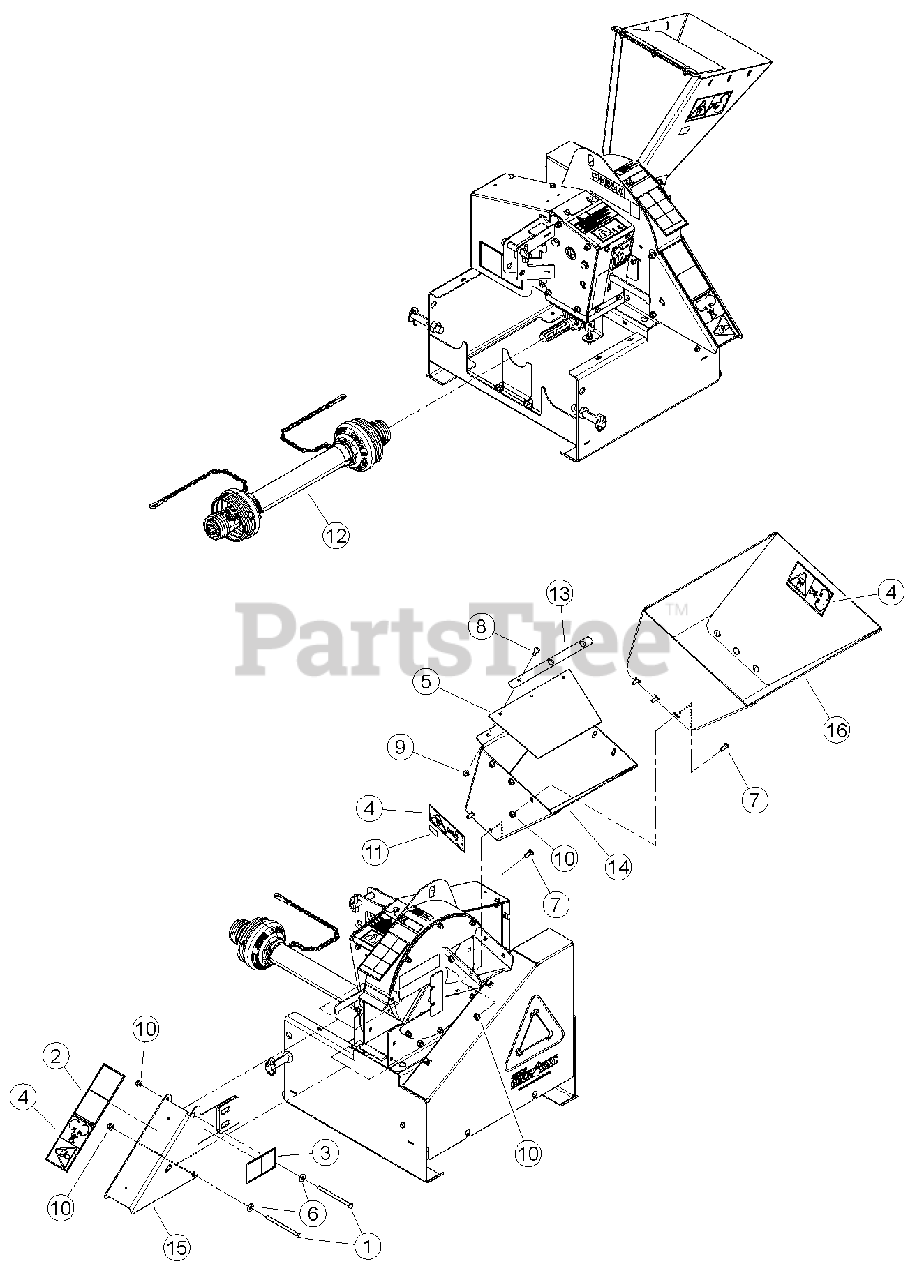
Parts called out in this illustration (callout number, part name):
1	BOLT, 3/8 X 5-1/2 HEX GR5 ZP
2	DECAL, KNIFE ACCESS ISO
3	DECAL, DISCHARGE ISO
4	DECAL, BLADE DANGER ISO
5	FLAP, CHIPPER CHUTE
6	WASHER, 3/8" FLAT ZP
7	BOLT, 3/8 X 1" CRG GR5 NC ZP
8	BOLT, 5/16" X 1" GR5 CRG ZP
9	NUT, 5/16-18 NYLOCK FLANGE
10	NUT, 3/8-16 NYLOCK FLANGE
11	DECAL, CE APPROVAL
12	DRIVELINE, 22.0/30.4" 1-3/8 SPL
13	STRIP, FLAP RETAINER
14	ASSEMBLY, HOPPER
15	ASSEMBLY, DISCHARGE CAP
16	ASSEMBLY, EURO CHUTE EXT. (CE ONLY)
